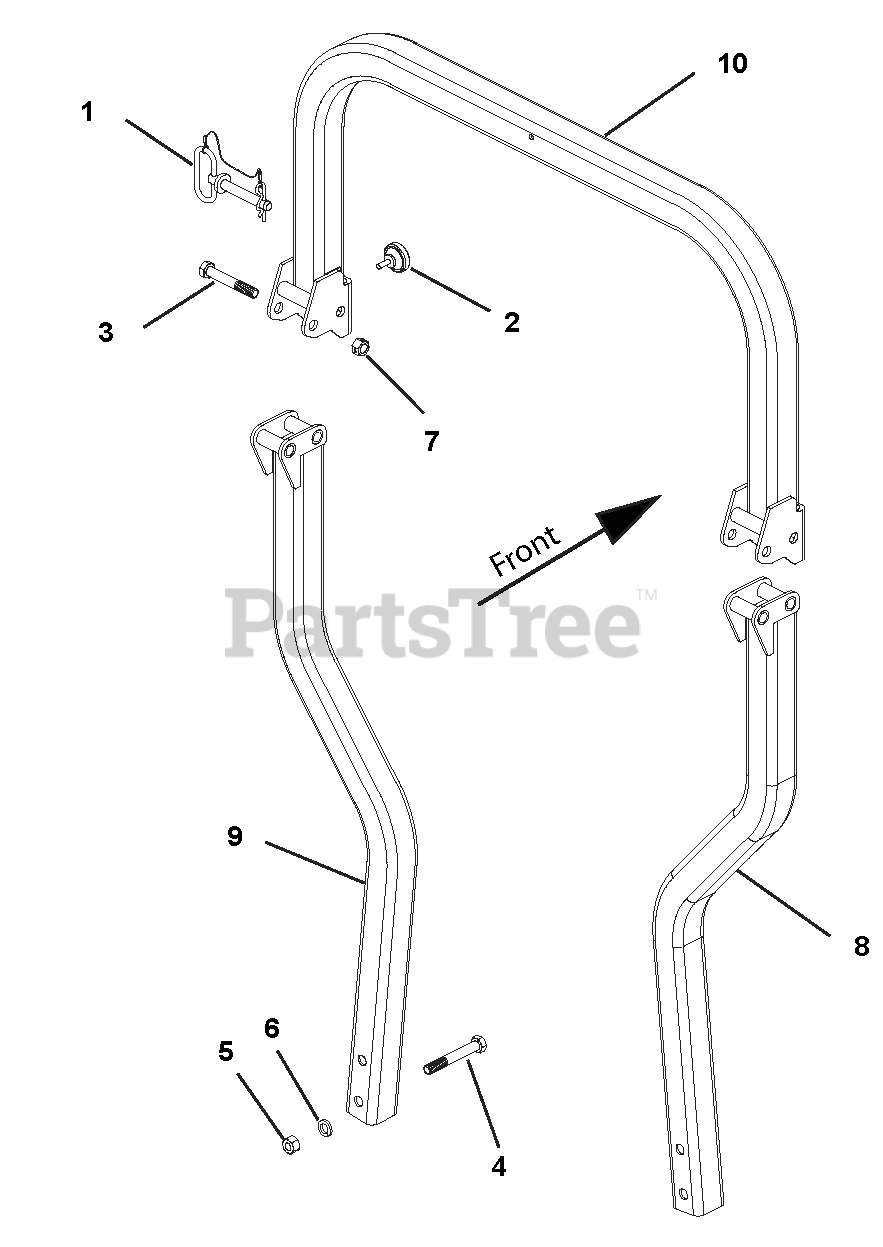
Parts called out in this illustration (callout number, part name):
1	ASSY, ROPS LOCK PIN S/O
2	KNOB, ROUND 5/16-18 X .750
3	@BLT-HEX .50-13X3.25 GR5 YWZC
4	@BLT-HEX .50-13X3.50 GR5 YWZC
5	@NUT-HEX .50-13 YWZC
6	@WSHR-LK .50X.125 REG YWZC
7	@NUT-LK-CTR .50-13 YWZC
8	Right Side Base Weldment
9	Left Side Base Weldment
10	Center Tube Weldment
